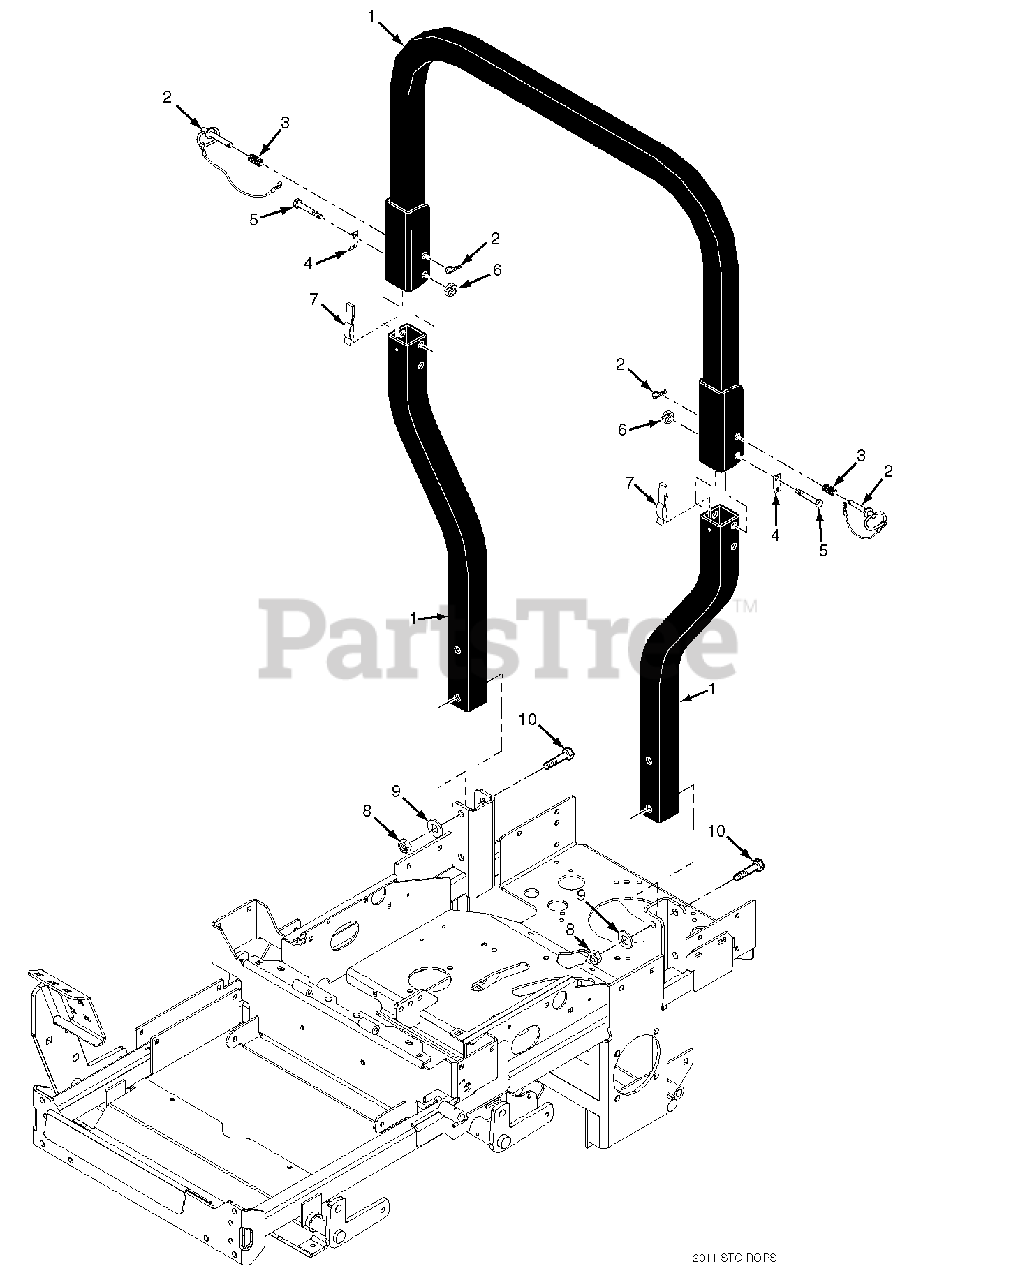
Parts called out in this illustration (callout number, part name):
1	STC Foldable ROPS
2	Pin Assembly
3	Spring, ROPS
4	Clip, ROPS
5	Bolt, Hex Head 1/2-13 x 3-1/4"
6	Nut, Center Lock 1/2-13
7	Spring Clip, ROPS
8	Nut, Center Lock 1/2-13
9	Flatwasher, 1/2-.562 x 1.375 x .109
10	Bolt, Hex Head 1/2-13 x 3-1/2"
